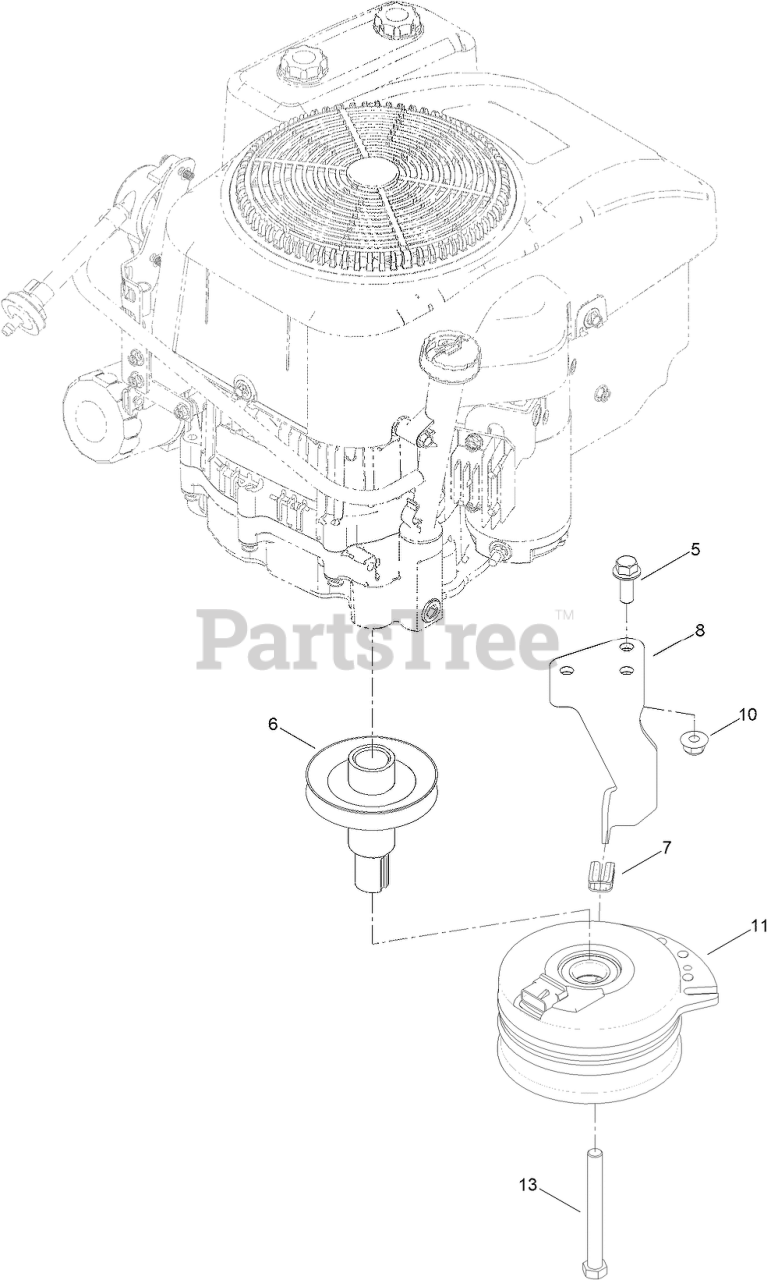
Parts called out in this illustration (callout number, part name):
5	SCREW-HHF
6	PULLEY-ENGINE
7	ISOLATOR-CLUTCH
8	STOP-CLUTCH
10	NUT-HF, NI
11	CLUTCH-ELECTRIC
13	SCREW-HH
